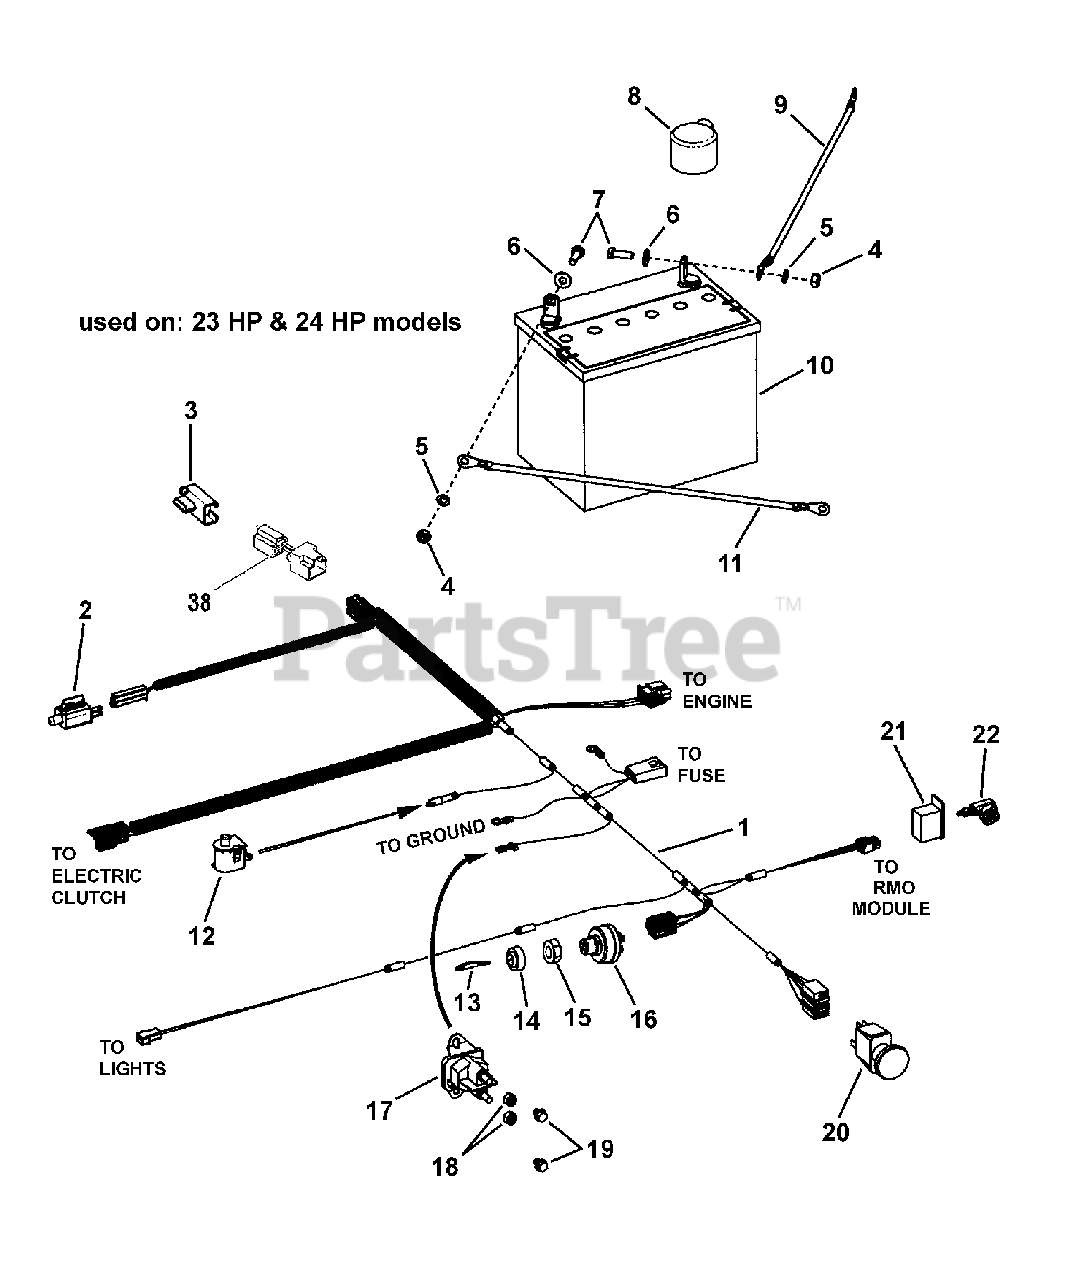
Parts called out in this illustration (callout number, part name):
1	HARNESS, Wiring, Hydro TCT, Elec PTO
2	SWITCH, Limit, NO, Snap-In
3	SWITCH, Limit, NO/NC, Snap-In
4	NUT, 1/4-20 NC-2B Hex
5	LOCKWASHER, 1/4"
6	WASHER, 1/4" Flat
7	BOLT, 1/4-20 x 3/4" Hex Head Cap, GR 5
8	BOOT, Battery, Positive
9	CABLE, Battery 8GA 18.00L - Red
10	BATTERY, 12 Volt, 230 CCA
11	CABLE, Battery 8GA 12.00L - Black
12	SWITCH, Seat NC
13	KEY, Ignition (set of 2)
14	CAP, Ignition Switch
15	NUT, 5/8-32 E-Start
16	SWITCH, Ignition-Afterfire Solenoid
17	SOLENOID, 3 Pole
18	NUT, 1/4-20 Hex Nyloc, BZ
19	SCREW, 1/4-14 x 3/8" Hex Washer Self-Tap
20	SWITCH, PTO, Yellow, Vertical Symbols
21	SWITCH, RMO Module Only
22	KEY, RMO Module Plastic
38	WIRE ASSEMBLY, Jumper
